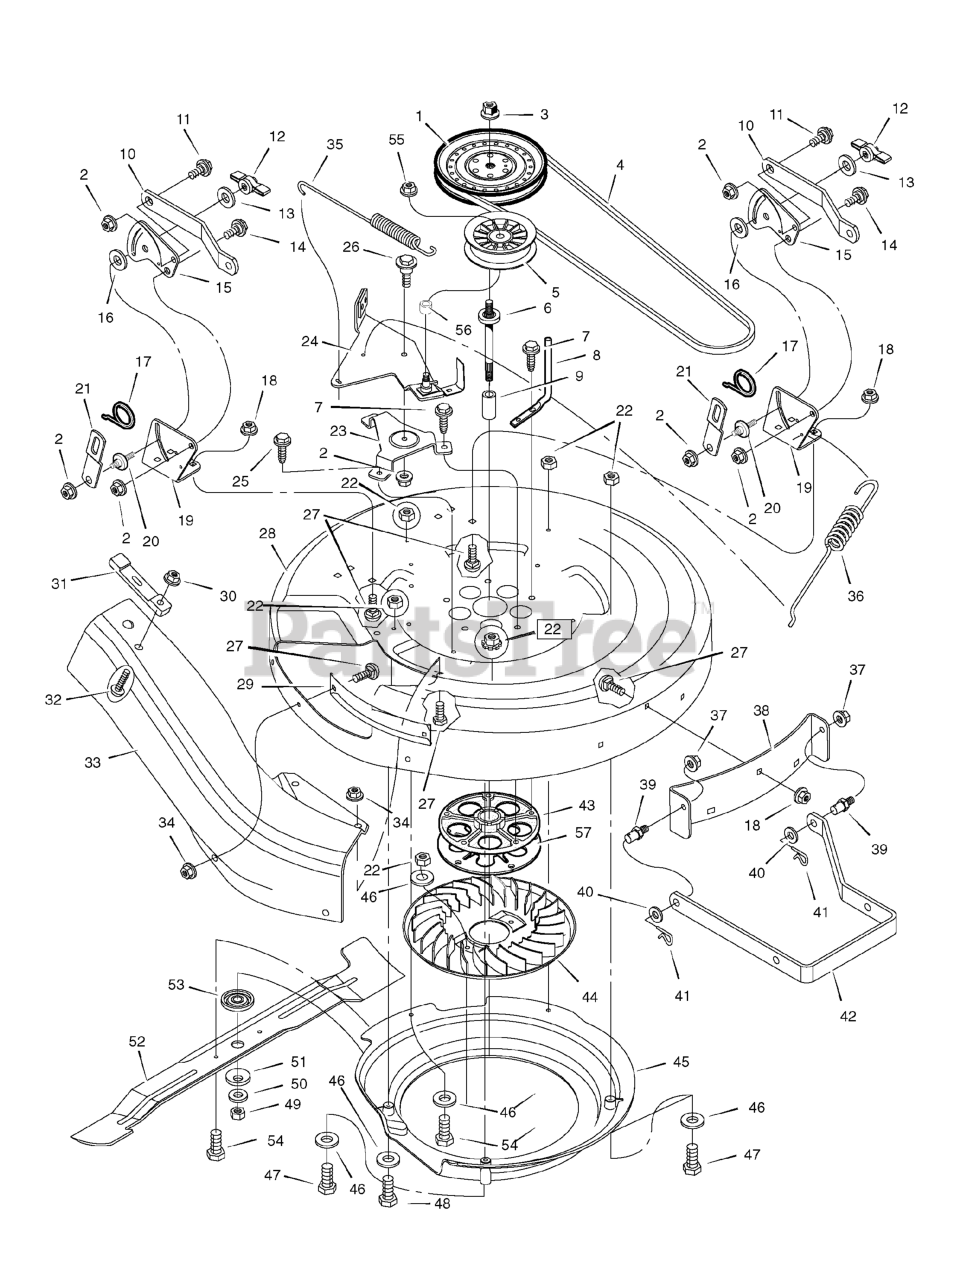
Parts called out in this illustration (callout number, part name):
2	Nut, Flange
4	Belt, Blade
5	Pulley, Idler
6	Mandrel
8	Guide, Belt
10	Bracket, Rear Suspension
11	Bolt, Shoulder
12	Knob
14	Bolt, Shoulder
15	Plate, Suspension
16	Pad, Friction
18	Nut, Flange
19	Bracket, Rear Deck
20	Pin, Hanger
21	Link, Lift
22	Nut
23	Bracket, Idler Arm
24	Assembly, Idler Arm & Pad
26	Bolt, Shoulder
27	Bolt, Carriage
28	Housing, Blade
30	Nut, Flange
31	Strap, Rubber
32	Screw
34	Nut
35	Spring, PTO
36	Spring, Extension
37	Nut, Flange
38	Bracket, Front Deck
39	Pin, Threaded Shoulder
41	Pin, Hair
42	Hanger, Front
43	Housing, Jackshaft
44	Fan, Assist
45	Housing, Fan
46	Washer
47	Bolt
48	Bolt
51	Washer, Belleville
53	Adapter, Blade
54	Bolt
55	Nut, Flange
57	Plate, Jackshaft Support
